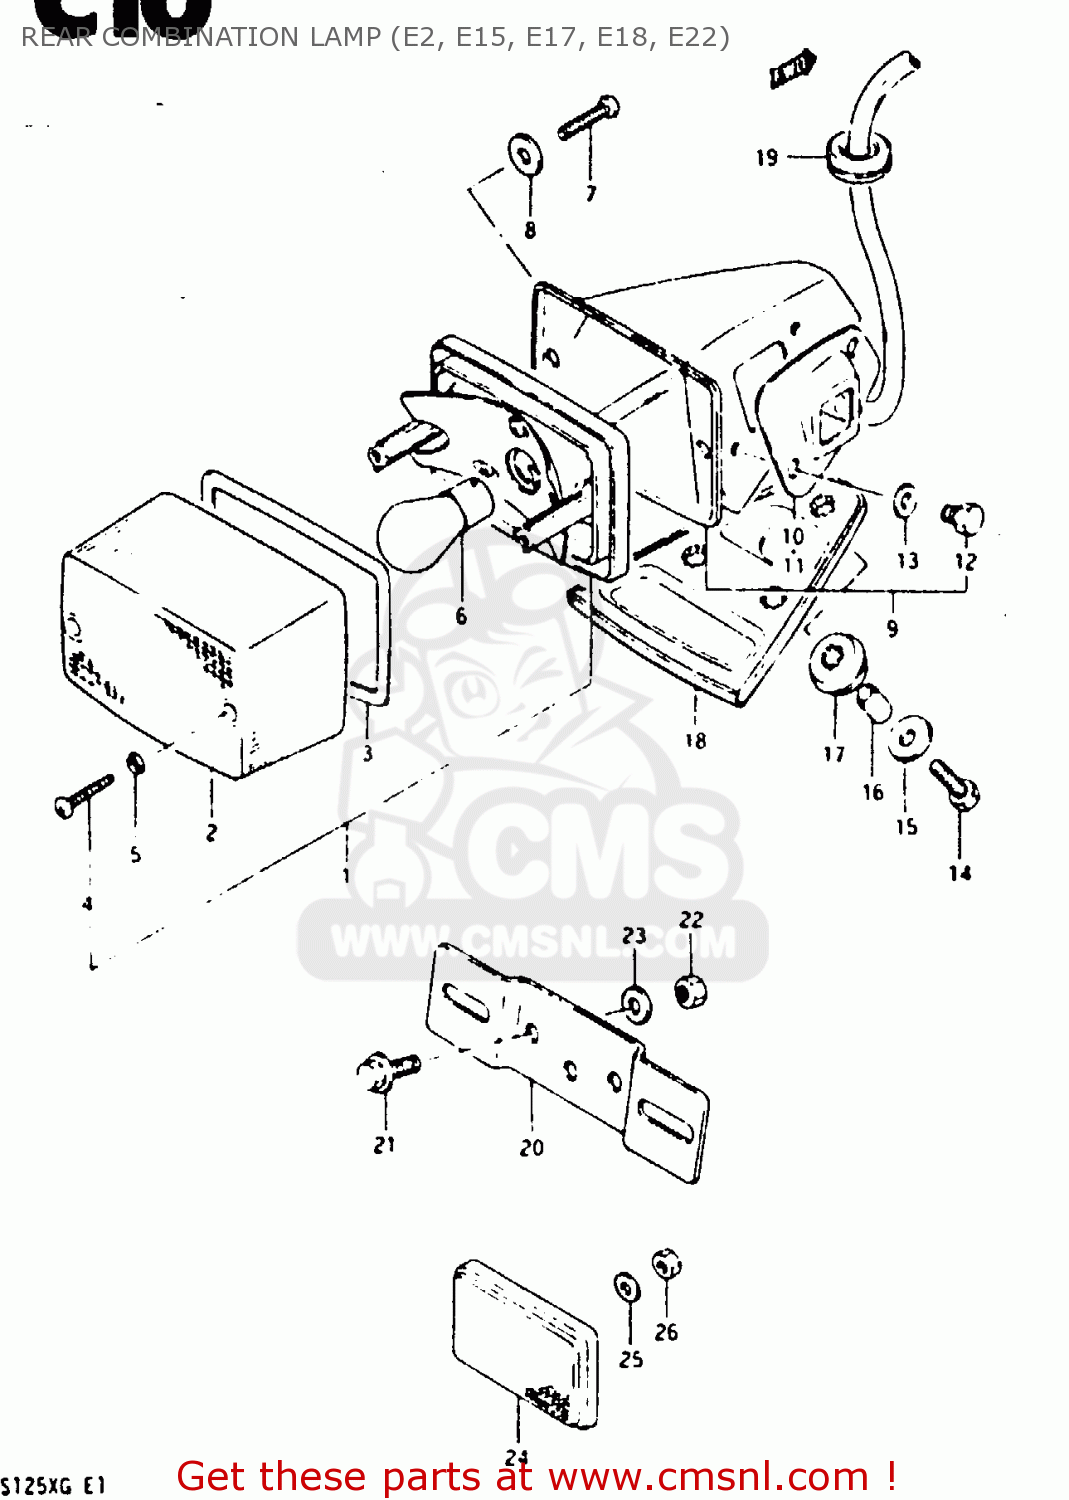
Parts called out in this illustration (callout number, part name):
1	LAMP UNIT, REAR COMBINATION
2	LENS,LAMP RR
3	GASKET,RR COMBI LAMP LENS (NAS)
4	SCREW
5	GASKET (NAS)
6	BULB(12V21/5W)
7	SCREW
8	WASHER
9	BRACKET UNIT
10	PLATE, RH
11	PLATE, LH
12	BOLT
13	WASHER
14	BOLT
15	WASHER (6.5X20X1.2)
16	SPACER (6.4X9X15.5)
17	CUSHION
18	CUSHION
19	GROMMET
20	BRACKET,PLATE LICENSE
21	BOLT
22	NUT
23	WASHER (6.5X20X1.2)
24	REFLEX REFLECTOR,RR
25	WASHER
26	NUT
